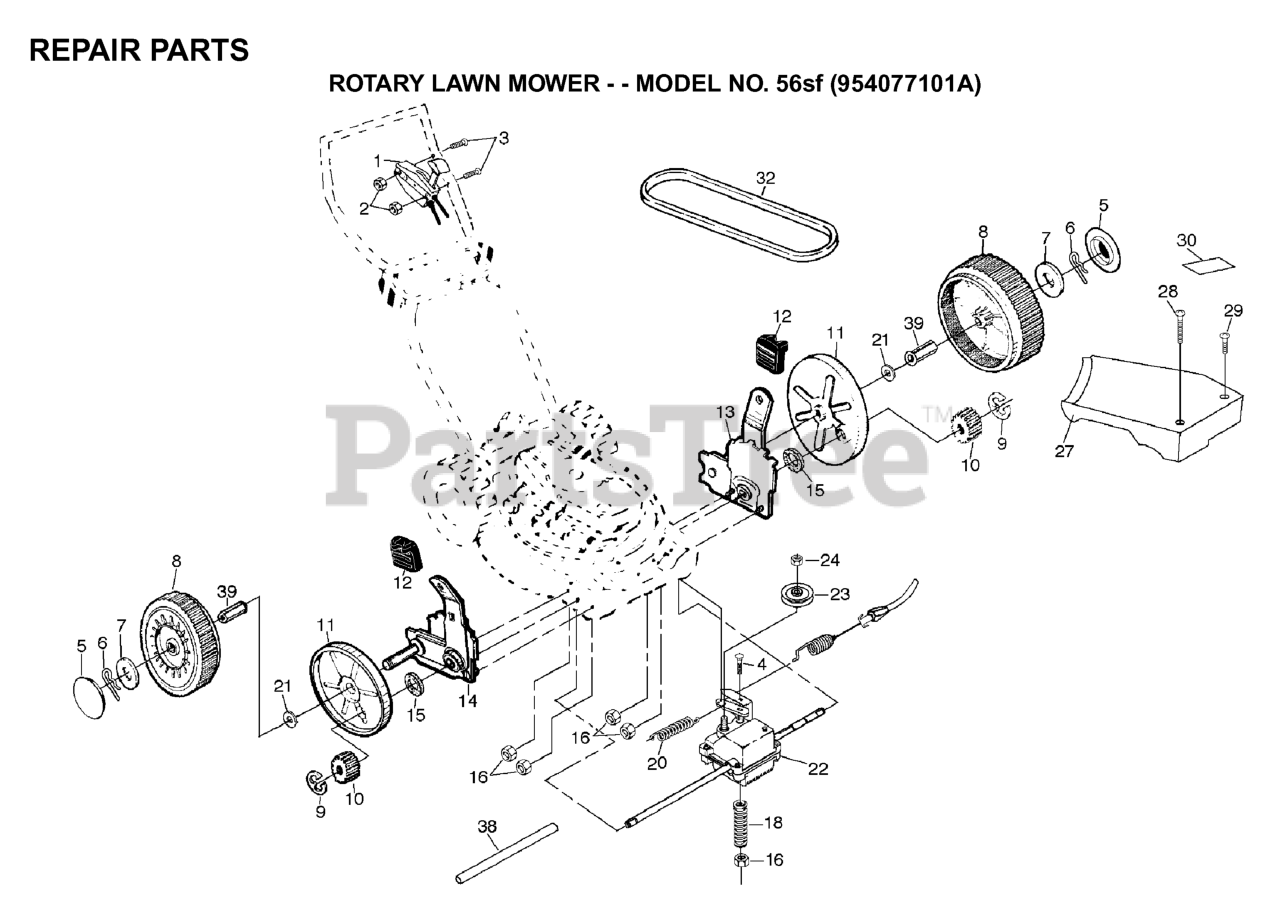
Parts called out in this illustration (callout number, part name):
1	DRIVE CONTROL
2	NUT
3	SCREW 1/4-20 X 2.12
6	RETAINER CLIP PM
8	DRIVE WHEEL
9	E-RING 7/16 RE
10	PINION GEAR
11	DUST SHROUD PM
12	SELECTOR KNOB
13	WHEEL ADJUSTER ASSY (LEFT)
14	WHEEL ADJUSTER KIT RH
16	NUT
18	SPRING.EXTENSION
21	WASHER FLUT
22	GEAR CASE ASMBLY
23	PULLEY
24	FLANGED LOCKNUT 3/8-16 ZINC
27	DRIVE COVER-GRAY
29	SCREW
32	BELT DRIVE
38	DRV SHAFT TUBE PM
39	BUSHING.1.860 X .505.
